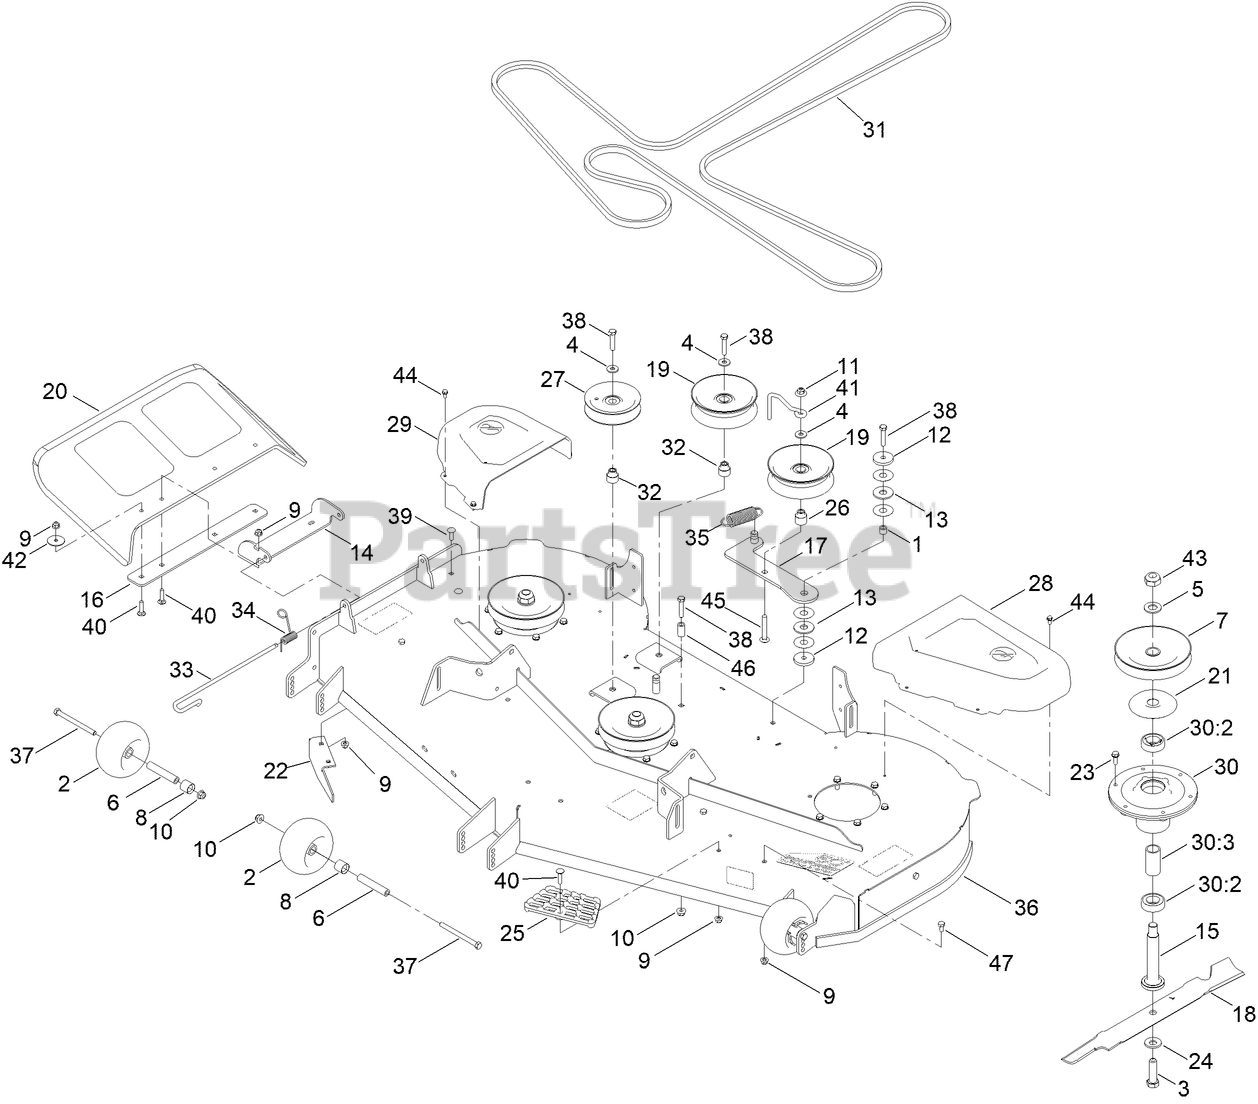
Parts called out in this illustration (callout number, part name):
1	BUSHING-LEVER, LIFT
2	ROLLER-SCALP, ANTI
3	SCREW-BLADE
4	WASHER-HARDENED
5	WASHER
6	TUBE-SPANNER
7	SHEAVE-DRIVE, BLADE
8	SPACER-AXLE, REAR
9	NUT-HF, NI
10	NUT-HF, NI
11	NUT-FLANGE, NI
12	WASHER-PLAIN
13	WASHER-FRICTION, COMPOSITE
14	BRACKET-DEFLECTOR, UPPER
15	SHAFT-SPINDLE
16	PLATE-DEFLECTOR
17	ARM-IDLER
18	BLADE-HI FLOW, 20.5 INCH
19	IDLER-PULLEY, FLAT
20	DEFLECTOR
21	SHIELD-BEARING
22	BAFFLE-CUTOFF
23	SCREW-TAPTITE
24	WASHER-BELLEVILLE
25	STEP-DECK
26	BUSHING-IDLER
27	PULLEY-IDLER, FLAT
28	COVER-BELT, LH
29	COVER-BELT, RH
30	SPINDLE ASM
30:2	BEARING-BALL
30:3	SPACER-BEARING
31	BELT-DECK DRIVE
32	BUSHING-IDLER
33	PIN-CHUTE
34	SPRING-TORSION
35	SPRING - EXTENSION
36	DECK ASM - 60
37	SCREW-HH
38	SCREW-HH
39	SCREW-CARR
40	SCREW-CARR
41	BELT GUIDE - IDLER
42	WASHER-FLAT
43	NUT-LOCK, NI
44	SCREW-HWH
45	SCREW-CARR
46	SPACER
47	SCREW-HHF
